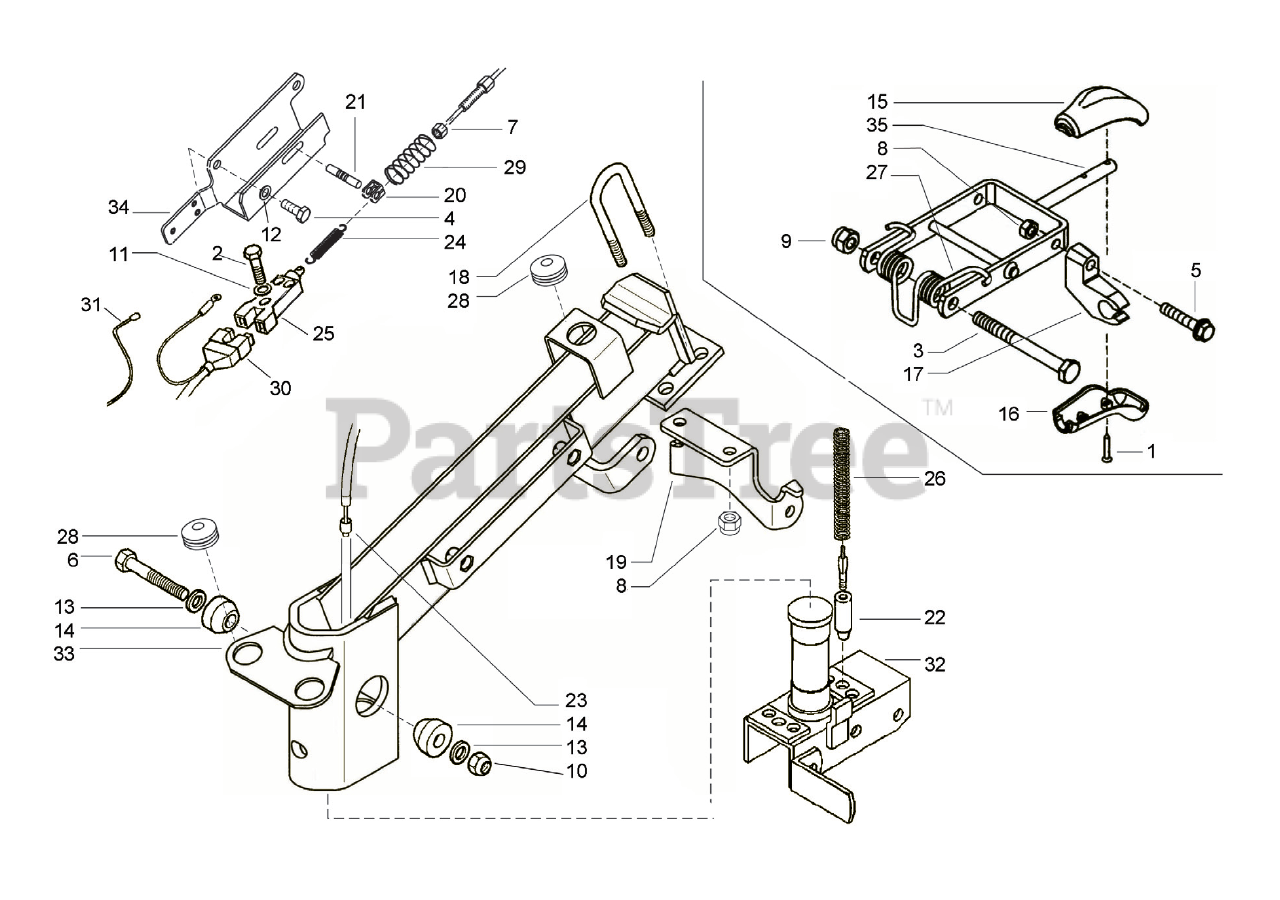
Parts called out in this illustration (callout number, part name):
1	SCREW 5X25
2	CAP SCREW, M4.7X25
3	CAP SCREW, M10X110
4	CAP SCREW, MX20
5	SCREW
6	CAP SCREW, M12X80
7	NUT, M8
8	LOCK NUT, M8
9	LOCK NUT, M10
10	LOCK NUT, M12 DEFORMED
11	WASHER, FLAT, M4
12	WASHER, SUPER M8
13	SPRING WASHER
14	WEDGE
15	UPPER HANDLE HALF, BLACK
16	LOWER HANDLE HALF, BLACK
17	SUPPORT, CONTROL ROD
18	U BOLT
19	BRACKET
20	MOTOR STOP FORK
21	SPRING CHECK PIN
23	SHEATH END
24	SPRING, STOP
25	STOP SWITCH
26	SPRING, STEERING COLUMN
27	HANDLEBAR RELEASE SPRING
28	SUPPORT CAP
29	CHECK SPRING, MOTOR STOP
30	MOTOR STOP WIRING
31	WIRE, GROUND FOR S/N 794196+
32	SUPPORT
33	STEERING COLUMN
34	SUPPORT, ENGINE STOP
35	LEVER, HANDLEBAR SELECTION
